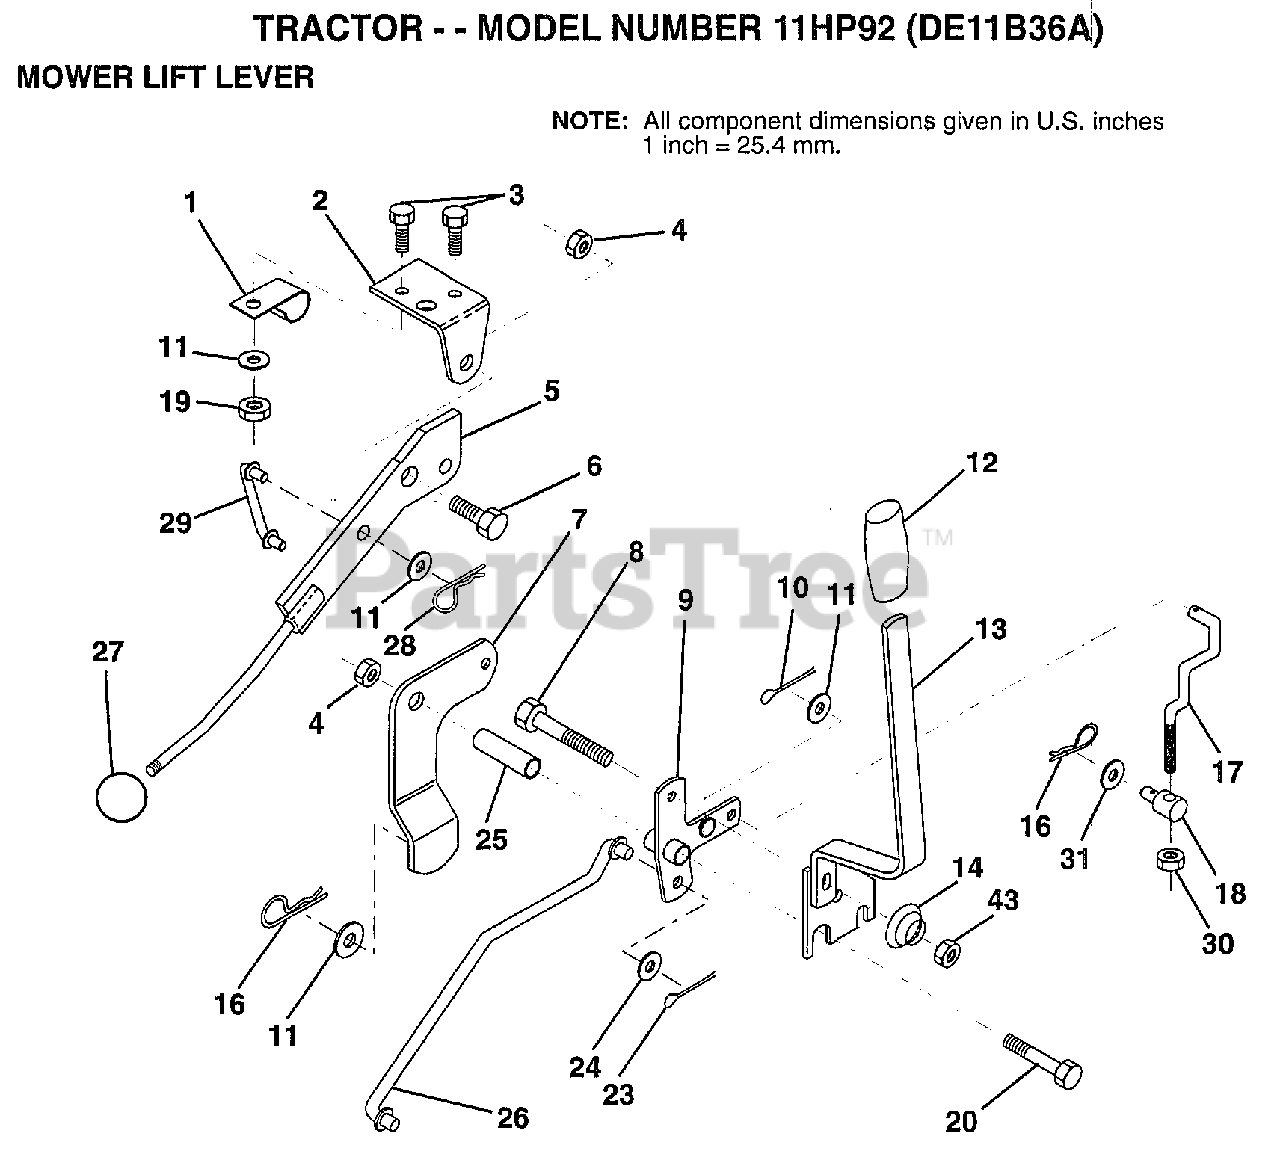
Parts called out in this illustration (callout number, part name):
1	"CLIP,INSULATOR"
2	BRKT CLUTCH
3	BOLT HXHD FIN
5	LEVER.ASM.CLUTCH
6	"BOLT, SHOULDER LT"
7	MWR CLUTCH ARM AS
8	BOLT
9	"BELLCRANK,LIFT"
10	COTTER PIN
11	WASHER
13	HANDLE.ASM.LIFT
14	SPRING COMPRESSIO
15	WASHER T
16	SPRING.RETAINER
17	"LINK,LIFT FRT"
18	TRUNION ADJ
20	BOLT
23	PIN COTTER 1/8
25	TUBE SPACER
26	ROD LIFT MOWER
27	KNOB T(3/8 HOLE)
28	RETAINER M
29	CLUTCH LINK
30	NUT
31	WASHER
